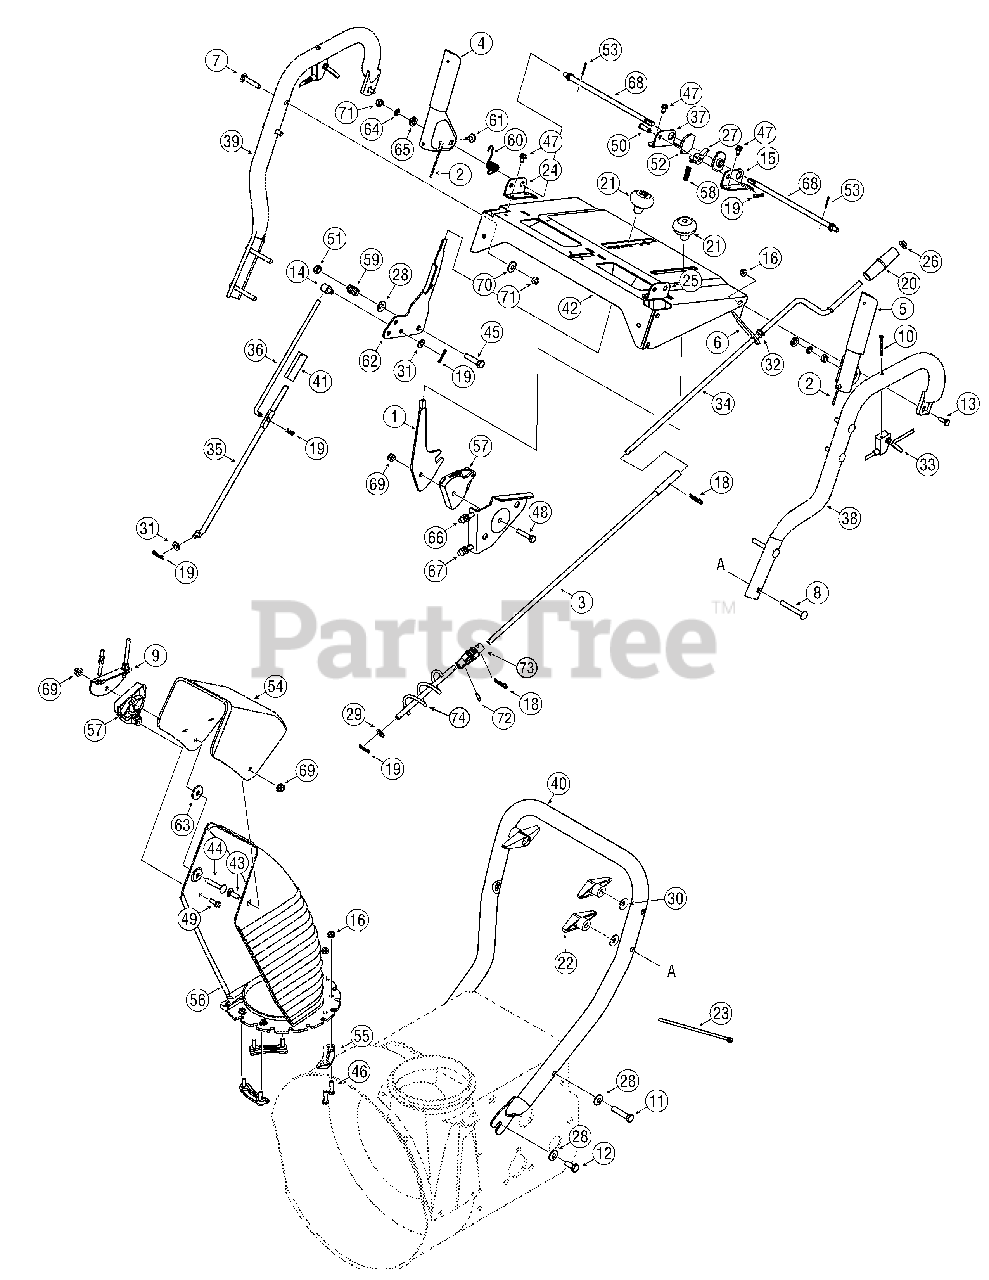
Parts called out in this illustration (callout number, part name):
1	Chute Tilt Handle
2	Cable Ass’y (Auger/Drive)
3	Lower Chute Crank Assembly
4	Engagement Handle RH Black
5	Engagement Handle LH Black
6	Upper Chute Crank Support
7	Carriage Bolt 5/16-18 x 1.75" Lg.
8	Carriage Bolt 5/16-18 X 2.50
9	Cable Bracket Chute Tilt
10	Screw, #10-24 x 1.75
11	Hex Screw 3/8-16 x 2.0 Gr. 5
12	Hex TT Screw 3/8-16 x .75
13	Hex Cap Bolt 1/4-20 x .75" Lg.
14	Adjustment Ferrule
15	LH Handle Support Brkt. 5/8"
16	Hex L-Flanged Nut 1/4-20 Gr. F Nylon
18	Internal Cotter Pin
19	Int. Cotter Pin .072 x 1.13" Lg.
20	Knob 1.0 x 3.2
21	Shift Knob
23	Cable Tie
24	RH Handle Support Brkt. 3/8"
26	Push Nut 3/8" Rod
27	Cam Lock Pawl
28	Cupped Washer .375 ID x .870 OD x .063
29	Flat Washer .406" I.D. x .75" O.D.
30	Cupped Washer .345 ID x .88 OD x .06
31	Flat Washer .34 ID x .688 OD x .065
32	Plastic Bushing .380 ID
33	Steering Trigger
34	Upper Chute Crank Assembly
35	Lower Shift Rod
36	Upper Shift Rod
37	RH Handle Support Brkt. 5/8"
38	Upper Handle LH
39	Upper Handle RH
40	Lower Handle
41	Connector - Shift Rod
42	Handle Panel Support Ass’y
43	Carriage Bolt 5/16-18 x 1.00" Lg
44	Carriage Bolt 5/16-18 x 1.75" Lg.
45	Hex Scr 3/8-24 x 1.50
46	Screw 1/4-20 x 1.0
47	Hex Wash S-Tapp Scr 1/4-20 x .50
48	Hex Bolt 5/16-18 x 1,50" Lg. Gr. 5
49	Hex Tapp Scr 1/4 x .75" Lg.
50	Clevis Pin .31 Dia. x 1.0" Lg.
51	Hex Nut 3/8-24
52	Cam Handle Lock
53	Cotter Pin 3/32 x .75
54	Upper Chute
55	Chute Flange Keeper
56	Lower Chute
57	Cable Guide
58	Compression Spring .62 OD x 6.12" Lg.
59	Compression Spring .38 ID x .88 Lg
60	Torsion Spring
61	Rubber Bumper
62	Shift Lever
63	Flat Washer .344 ID x 1.125 OD x .125
64	L-Wash 5/16 ID
65	Flat Washer (special) .350 sq. x .72 x .134
66	Chute Control Cable 66"
67	Chute Control Cable w/clip
68	Cam Rod
69	Hex L-Flanged Nut 5/16-18 Gr. F Nylon
70	Flat Washer .349 ID x .879 OD x .063
71	Hex Patch L-Nut 5/16-18
72	Spiral Pin .156 Diam x .80" Lg.
73	Joint Block Ass'y
74	Chute Crank Assembly
